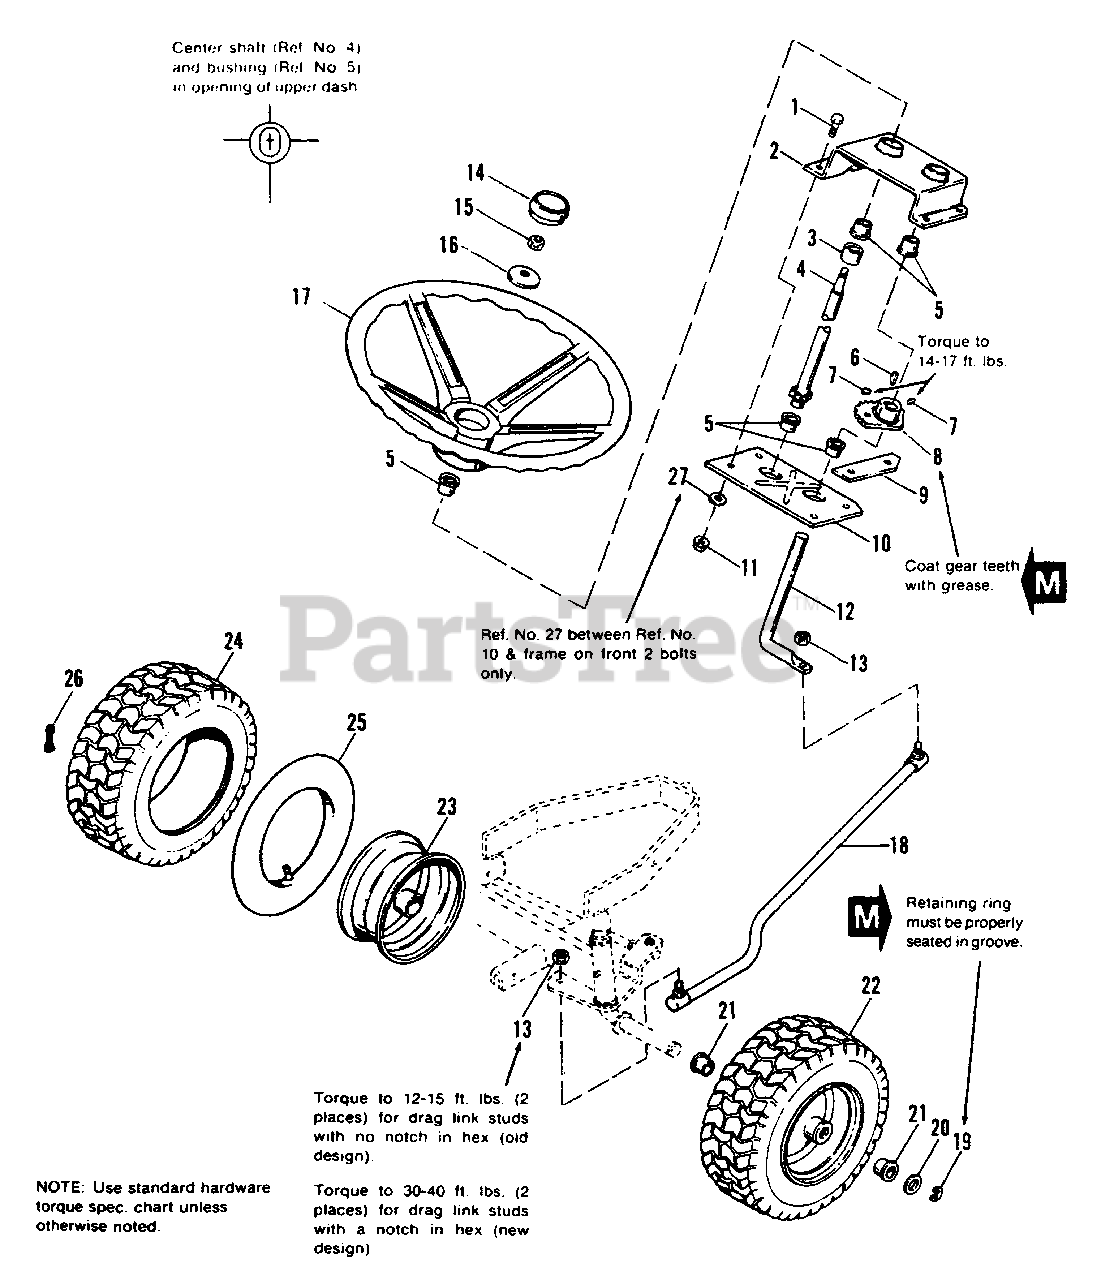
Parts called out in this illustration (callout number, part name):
1	CAPSCREW, 5/16-18 x 1
2	TOP PLATE, Steering
4	SHAFT ASSY., Steering
7	SETSCREW, 5/16-18 x 5/8
8	GEAR, Steering
9	SPACER, Stop
10	BASE PLATE, Steering
11	LOCKNUT, Flange Whiz. 5/16-18
12	ROD, Steering
13	LOCKNUT, Center, 3/8-24
14	CAP, Steering Wheel
15	LOCKNUT, 5/16-18
16	WASHER, Compression
17	WHEEL, Steering
18	LINK, Drag (6116 Only)
18	LINK, Drag (6108 & 6111 Only)
19	E-RING, Ext., 3/4
22	WHEEL & TIRE ASSY. 15 x 6.00-6
23	WHEEL
24	TIRE, 15 x 6.00-6 (Carlisle)
24	TIRE, 15 x 6.00-6 (Goodyear)
25	TUBE, 4.10/3.50-6
26	STEM, Valve
27	WASHER, 11/32
